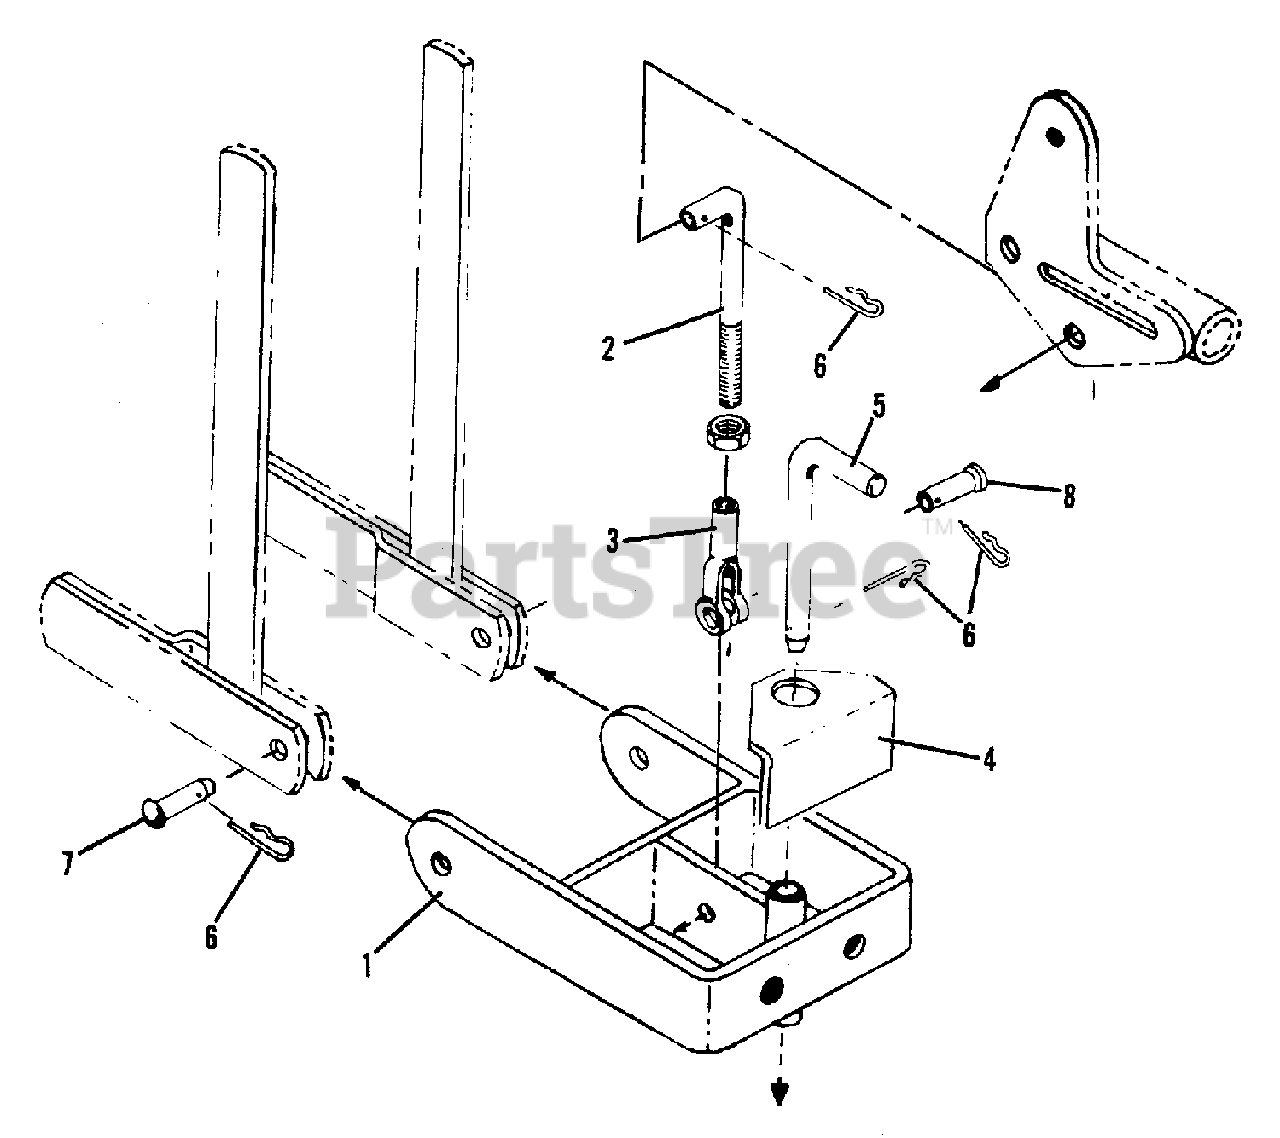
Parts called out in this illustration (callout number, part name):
1	CLEVIS ASSEMBLY, Hitch
1	CAPSCREW, 5/8NC x 2-1/4
1	NUT, 5/8NC, Jam
2	WASHER, 1/2 x 1-1/4 x #14
2	NUT, 1/2NF, Jam
3	YOKE, Lift Rod
4	PLATE, Stabalizer
7	PIN, Round Head
8	PIN, Yoke
